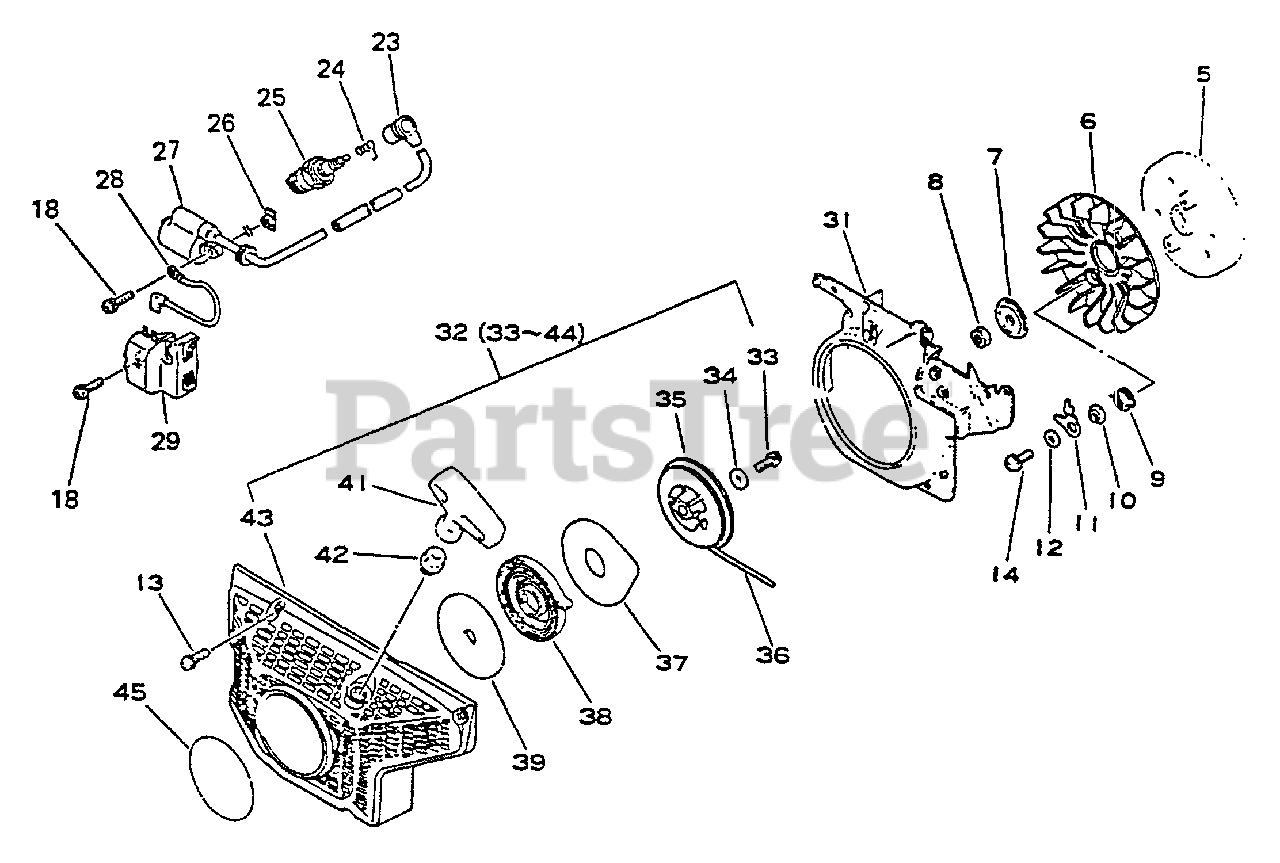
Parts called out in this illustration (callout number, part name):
5	FLYWHEEL
5	KEY, WOODRUFF
7	WASHER 8.2×31×0.8
9	SPRING, RETURN
10	SPACER, PAWL
11	PAWL, STARTER
12	WASHER 5.5×12×0.8
13	SCREW - 5×20
14	SCREW - 5×14
18	SCREW - 4×20
23	CAP, SPARK PLUG
24	TERMINAL, SPARK PLUG
25	SPARK PLUG - CJ-6Y
27	COIL, IGNITION
29	COIL, IGNITION
31	SHIELD, FAN
32	STARTER ASSY
33	SCREW - 5×14
34	WASHER 5.5×12×0.8
35	REEL, ROPE
36	ROPE, STARTER 4.0×950
37	PLATE, STARTER
38	SPRING, RECOIL
39	PLATE, STARTER
41	GRIP, STARTER
42	GUIDE, ROPE
43	CASE, STARTER
45	LABEL - ECHO
